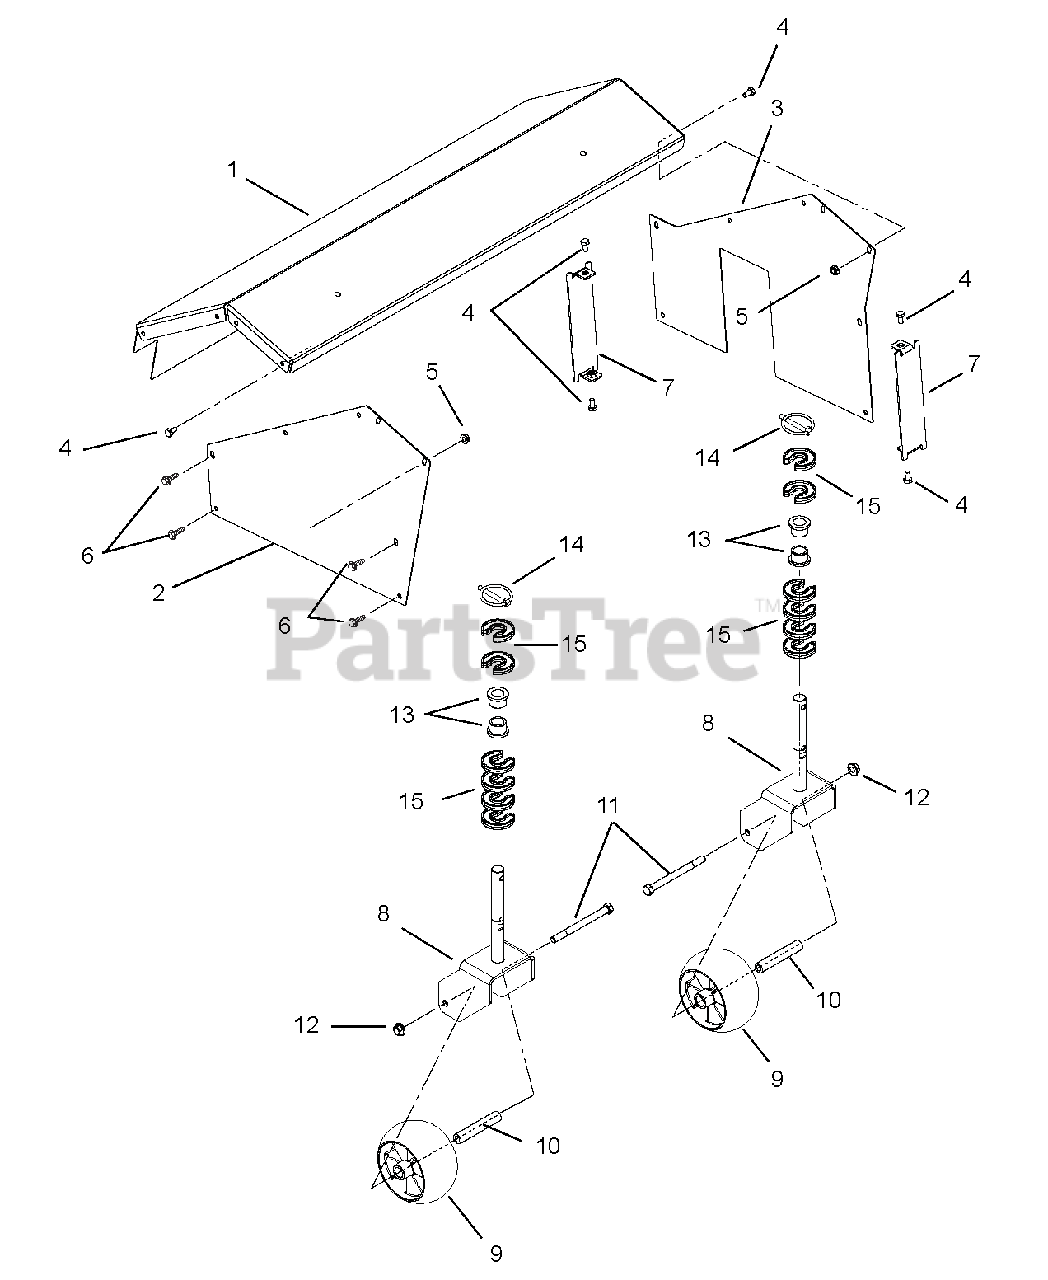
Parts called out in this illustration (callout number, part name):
1	COVER WITH DECALS, 28"BRUSH
2	COVER,RH SIDE BRUSH
3	COVER,LH SIDE BRUSH
4	@BLT-HEX .25-20X.50 GR5 YWZC
5	@NUT-LK-TOP-FLG .25-20 YWZC
6	SCR-TAP .25-20X.50 HWH TR YWZ
7	COVER,END
8	FORK, CASTER
9	ANTI-SCALP WHEEL - 5X3 CTR
10	SPACER, CASTER WHEEL
11	@BLT-HEX .38-16X4.50 GR5 YWZC
12	@NUT-LK-TOP-FLG .38-16 YWZC
13	BUSHING, FLANGE .75X.75X1.0
14	PIN, LYNCH - .25 X 1.25
15	CLIP-HOC FIXED
